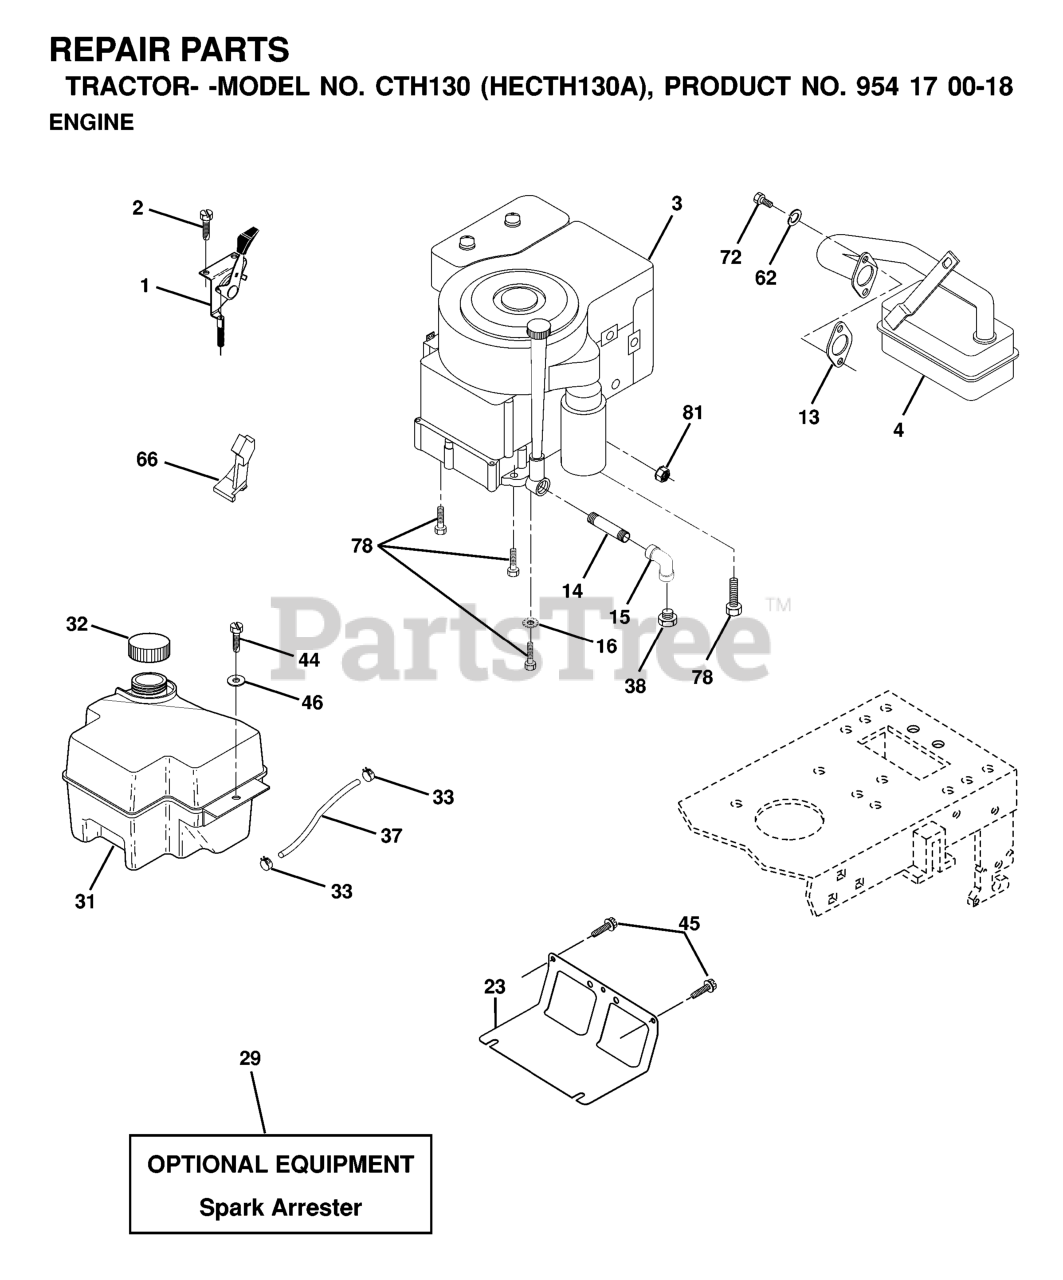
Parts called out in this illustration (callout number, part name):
1	CONTROL
2	SCREW LT
4	MUFFLER.SINGLE.B&S.10-12HP
13	REPL BY 532 27 22-93
14	Nipple Pipe 3/8 Npt X 3-1/2
15	ELBOW
16	LOCKWASHER
23	SHIELD.BROWNING.DBR.GUARD
29	KIT.SPARK ARRESTOR 794945 B&S
31	FUEL TANK
32	FUEL CAP
33	HOSE CLAMP
37	LINE.FUEL.20
44	SCREW HEX CRT
45	SCREW 3/8-16X3/4
62	WASHER.LOCK.HVY.HLCL.SPR.5/16
66	STOP THROTTLE
72	Screw, Hex.Hd. Cap 5/16 - 18 x 5/8
78	SCREW.3/8-16
81	NUT FLANGE 1/4-20 STARTER NUT
